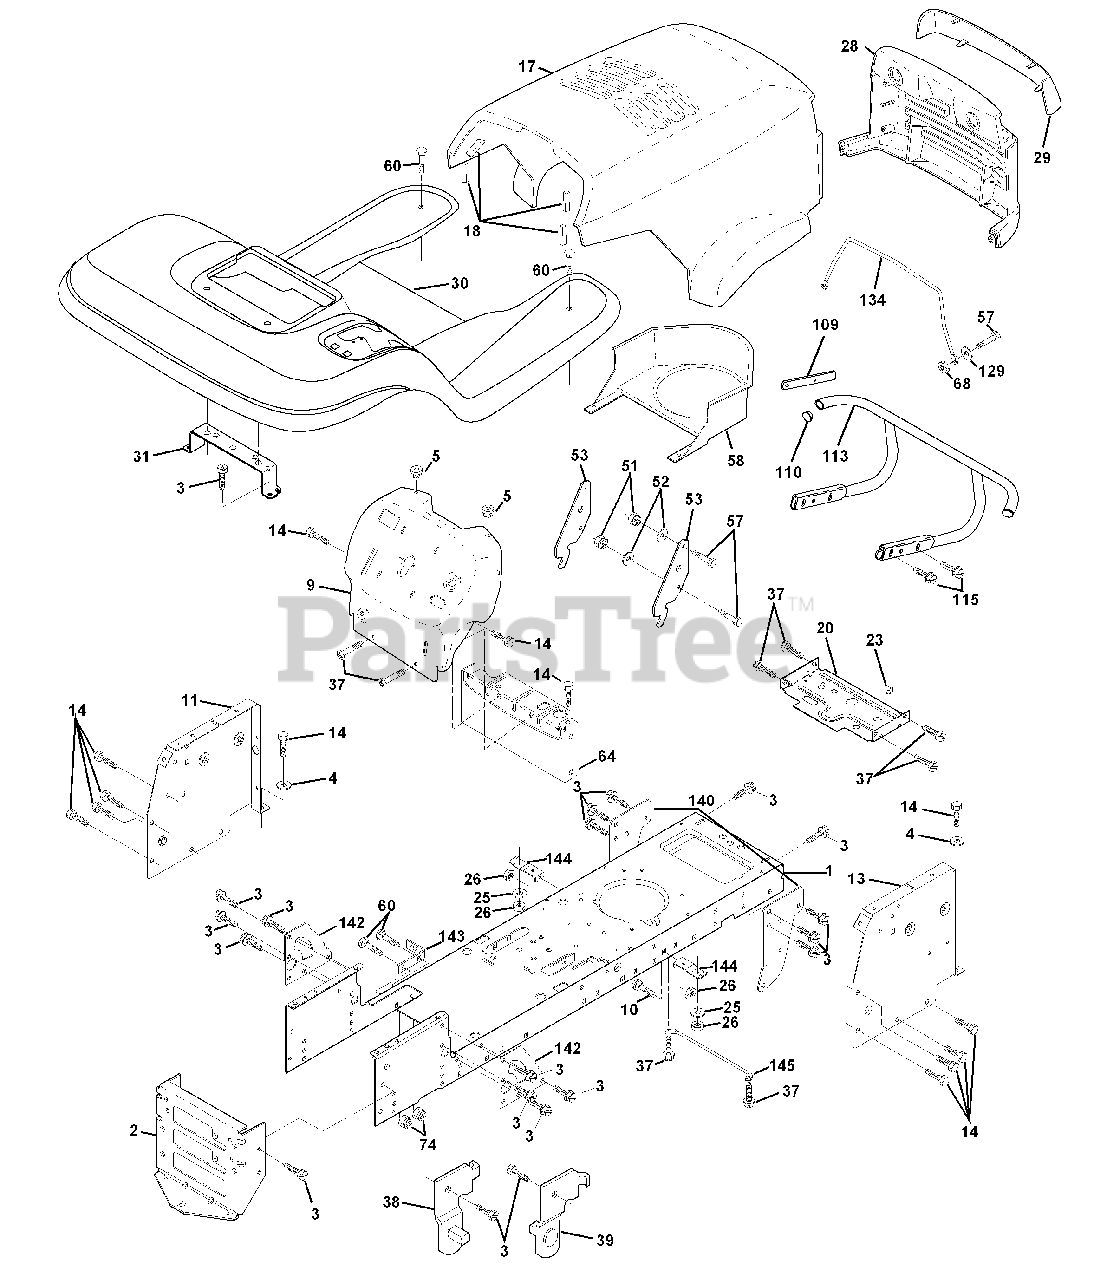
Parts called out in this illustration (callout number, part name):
2	Drawbar, Stretch
3	Screw Thdrol 3/8-16x3/4 Ty-tt
4	Washer 13/32 x 3/4 x 16 Ga.
5	Bumper Hood/Dash
9	Dash Slkscr
10	Bolt Carriage 3/8-16 x 1
11	Panel Dash Lh
13	Panel Dash Rh
14	Screw Thdrol 3/8-16x1/2 Ty-tt
17	Hood LT/PL Husqvarna
18	Bumper, Hood
20	Plate Mtg Battery Fuel Tank Fr
25	Washer 13/32 X 13/16 X 12 Ga
26	Nut Lock Hex W/Ins 3/8-16 Unc
28	Grille LT/PL Husqvarna
29	Lens LT/PL Husqvarna
30	Fender Footrest STLT Pnt
31	Bracket Support Fender
37	Screw Thdrol 6/16-18 x 1/2 TYT
38	Bracket, Asm. Pivot, L.H., Mower Rear
39	Bracket, Asm. Pivot, R.H., Mower Rear
51	Nut Lock Hex W/Ins 1/4-20
52	Washer 9/32 x 7/8 x 16 Ga.
53	Bracket Pnt. Pick off LT/PL Husqvarna
57	Bolt Hex 1/4-20 x 3/4
58	Air Duct Engine CV18
60	Bolt Rdhd Sqnk 3/8-16unc x 3/4
64	Dash Lower STLT
68	Nut Keps Hex 1/4-20 Unc
74	Nut Crownlock 3/8-16 UNC
109	Bracket Extension Bumper
110	Plug Plastic
113	Bumper Asm.
115	Screw Thdrol 3/8-16 x 1/4 TYTT
129	Washer 9/32 x 5/8 x 16 Ga.
134	Rod Support Hood LT/PL Husq.
140	Bracket Chassis Front 7 Ga.
142	Plate Reinforcement STLT
143	Bracket Swaybar Chassis
144	Bracket Pnt Footrest STLT
145	Rod Pivot Chassis/Hood
